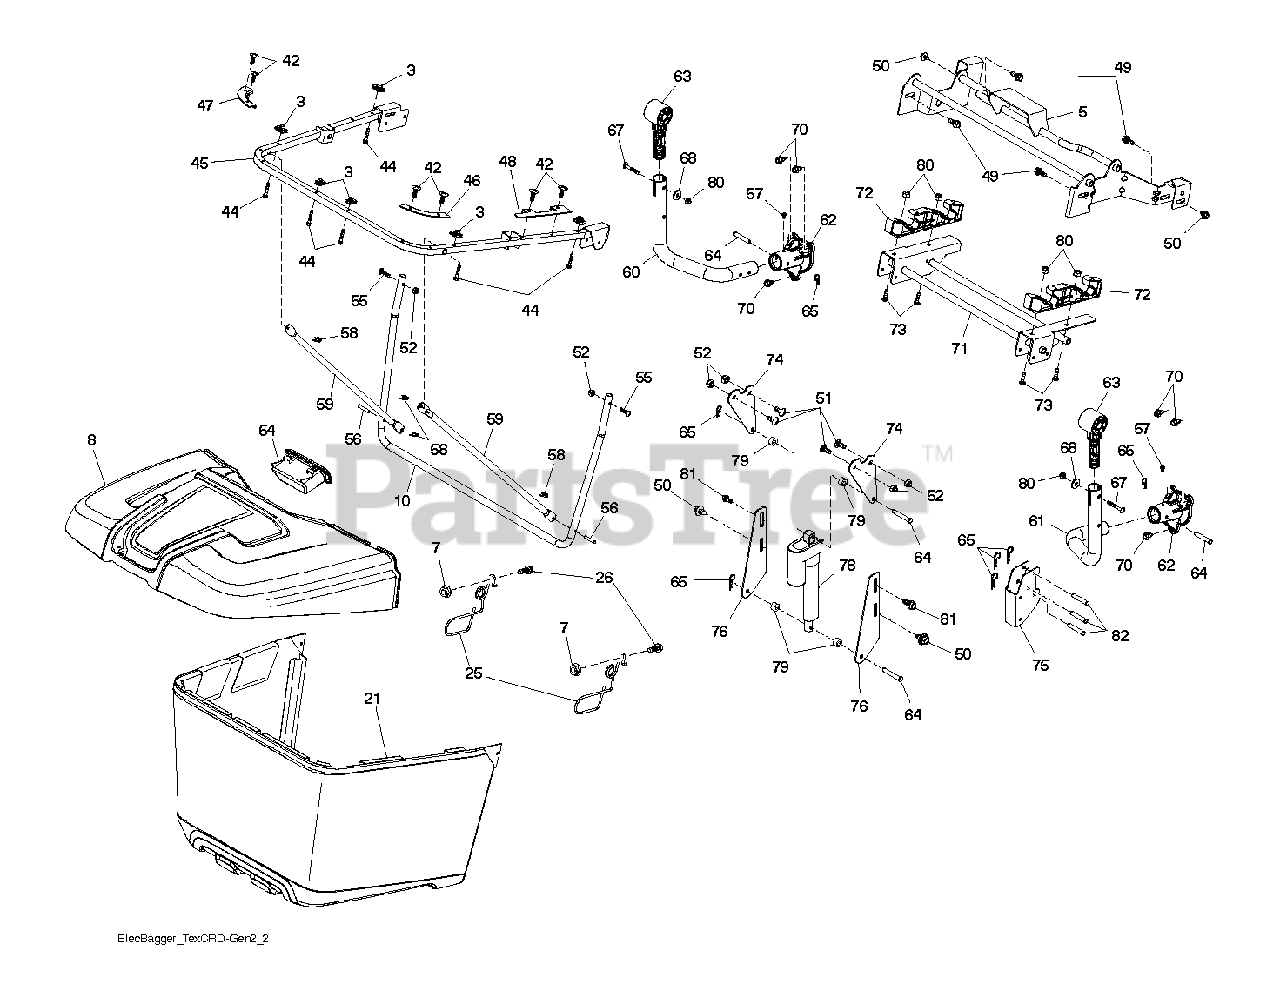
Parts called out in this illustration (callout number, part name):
7	NUT T
10	FRAME TEXCRDGEN2 BAGG
21	BAG BAGGER FABRIC ASS
25	LATCH LATCH. BAG. CRD
26	SCREW HEX CRT
42	CLIP CHRISTMAS TREE C
45	FRAME TEXCRDGEN2 UPPE
46	CONNECTOR LEFT BAGGER
47	CONNECTOR RIGHT BAGGE
48	BAFFLE BAGGER SIDE CL
49	BOLT, SHOULDER 5/16-18
50	BOLT, 5/16-18 X 1 3/4
52	NUT.71038.31-18.HEX.NYLOCK
54	BAGGER.TOP.FRONT.HAND
56	PIN.CLEVIS.183
57	SCREW T30 1420 X
58	RETAINER CLIP PM
59	TUBE BAGGER SPREADER
65	RETAINER M
70	SCREW, 3/8-16X3/4
73	BOLT.CARRIAGE.5/16-18
79	SPACER.NYLON.75" X .4375
80	NUT LOCK HEX FLANGE 5/16-18
81	SHOULDER BOLT 5/16-18TT
